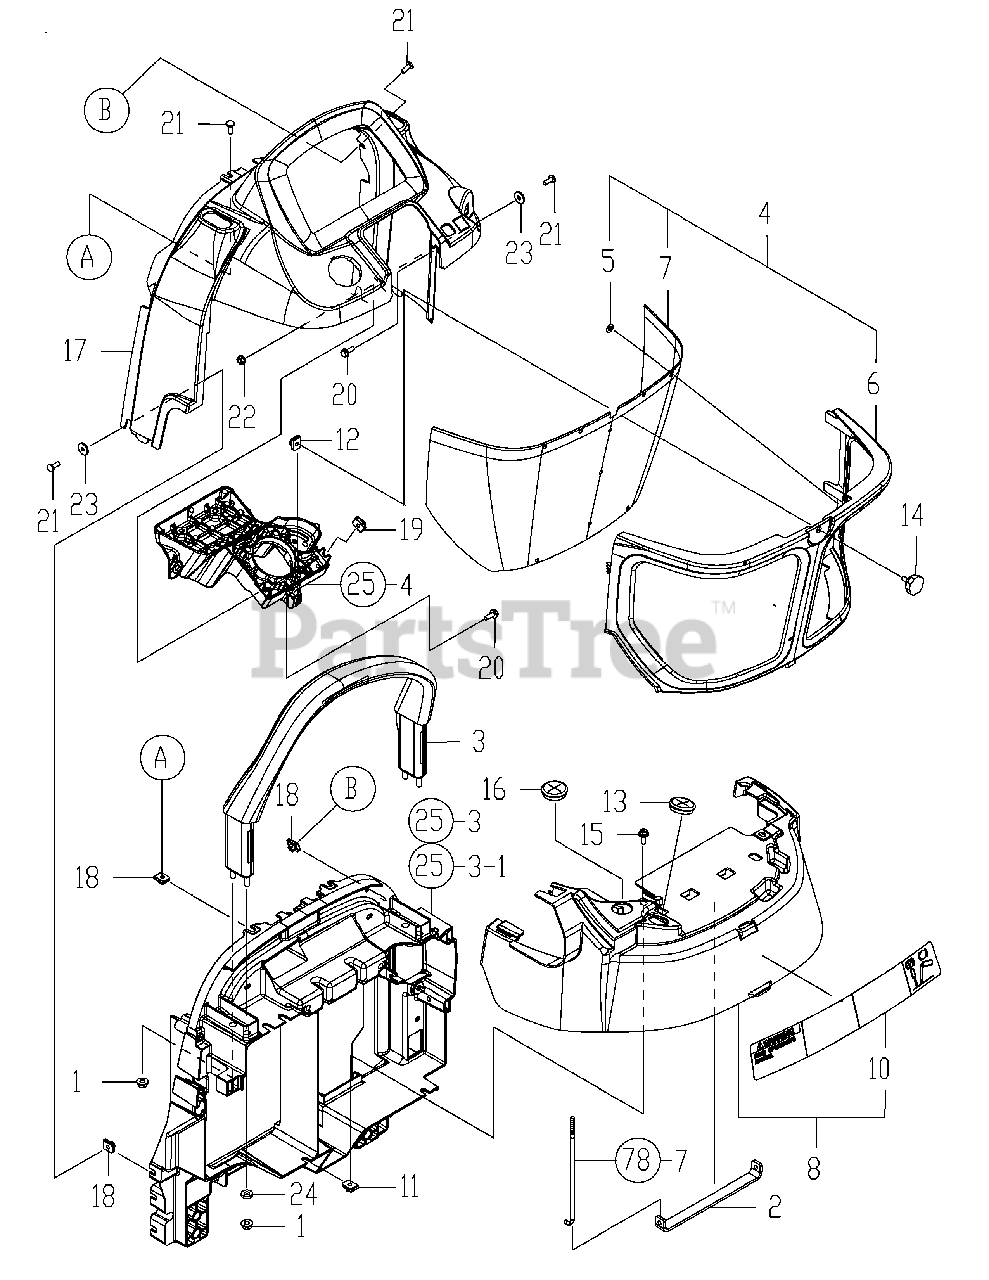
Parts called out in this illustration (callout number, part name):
4	DASHBOARD ASSY, L WR
5	NUT, 5
6	COVER, DASHBOARD LWR
7	NET, DASHCOVER
8	COVER M ASY, DASH BTM
10	LABEL, CAUTION, GENERAL
17	COVER, DASHBOARD UPPER
22	NUT W/WASHER 6
24	SPACER
